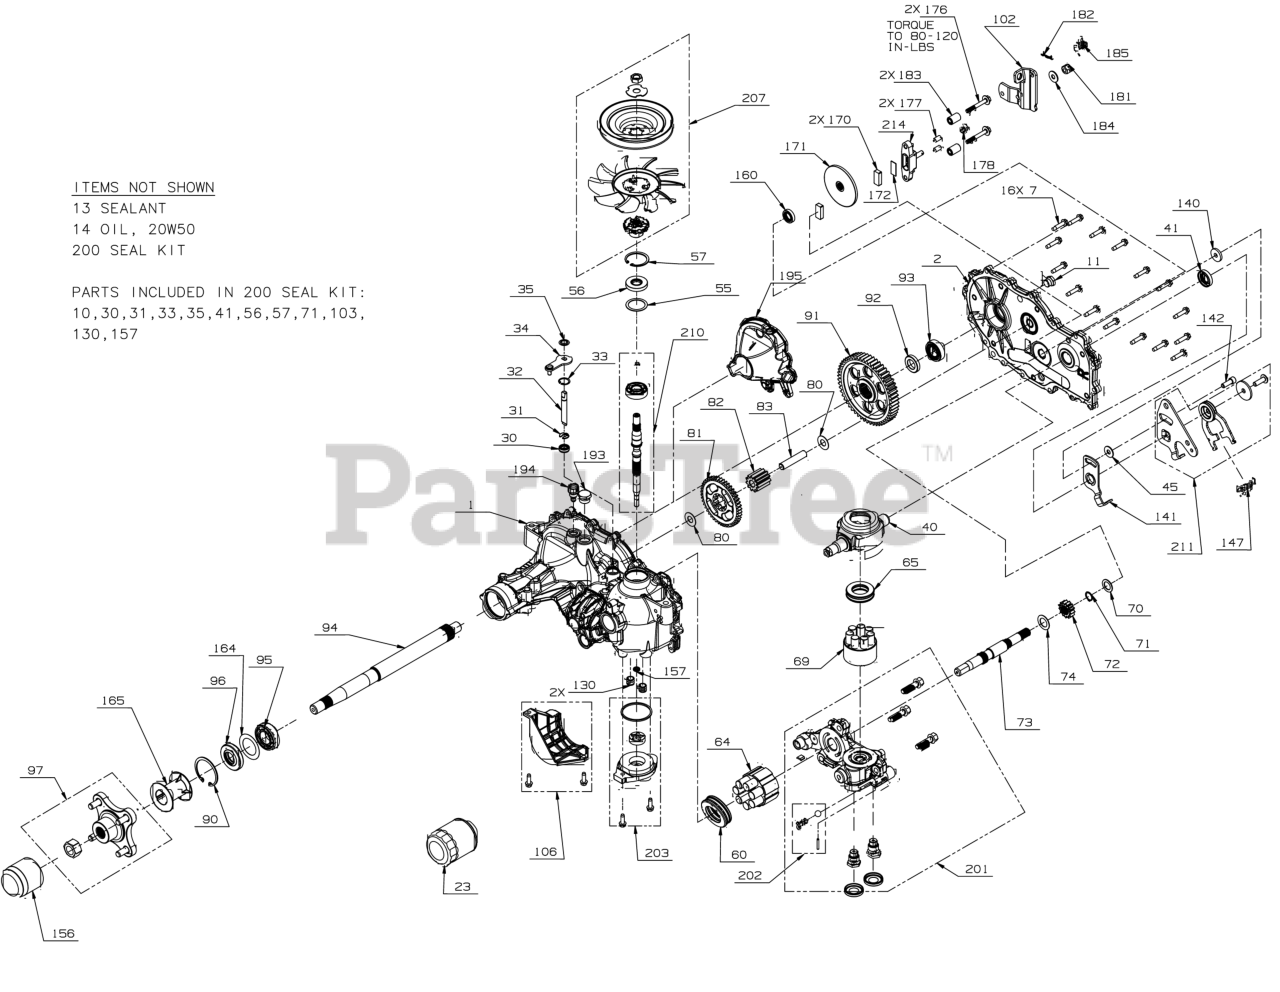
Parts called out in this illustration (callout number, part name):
1	MAIN HOUSING KIT (RH)
2	SIDE COVER KIT (RH)
7	SCREW-WASHER HEAD
11	VENT PLUG
13	SEALANT-HOUSING
23	OIL FILTER
30	SEAL-LIP .375 X .75 X .25
31	RETAINING RING
32	BYPASS RODS
33	RETAINING RING
34	ARM-BYPASS
35	RETAINING RING
40	SWASHPLATE-TRUNNION
45	FLAT WASHER
55	WASHER 1.23X1.56X
57	RETAINING RING
60	THRUST BEARING
64	CYLINDER BLOCK ASSEMBLY
65	THRUST BEARING
69	BLOCK KIT-CYLINDER
70	FLAT WASHER
71	RETAINING RING
72	GEAR - 13 TOOTH STEEL
73	MOTOR SHAFT
74	MOTOR SHAFT WASHER
81	GEAR - 46 TOOTH
82	GEAR-11 T
83	PIN-JACKSHAFT
90	RETAINING RING
91	GEAR - 54 TOOTH
92	SPACER .75X1.32X.257
93	BALL BEARING
94	AXLE SHAFT
95	BALL BEARING
97	HUB KIT-4 BOLT
102	ARM-BRAKE
106	FILTER GUARD KIT
130	TUBE-CHARGE TRIPLE O-RING
140	SPACER .32 x 1.005 x .179
141	ARM-NEUTRAL (LH)
142	SCREWS KIT-RTN
147	EXTENSION SPRING
157	KIT-GEROTOR SEAL
165	TUBE-AXLE 2.03
170	BRAKE PUCK
171	ROTOR-BRAKE
172	PUCK PLATE
176	BOLT-SPECIAL FLANG
177	ACTUATING PIN
178	BRAKE SPRING
182	COTTER PIN-3/32 DIA x .75
183	SPACER-TORSION SPG
184	FLAT WASHER
185	BRAKE SPRING
193	PLUG 3/4-16
194	BREATHER FITTING 9/16-18
195	EXPANSION TANK (RH)
201	CENTER SECTION KIT (RH)
202	KIT-CHARGE RELIEF
203	CHARGE KIT
207	FAN & PULLEY KIT
209	PULLER KIT-HUB
210	INPUT SHAFT KIT
211	RETURN KIT-NEUTRAL (LH) ZT2800 RZT
214	BRAKE YOKE ASSEMBLY
